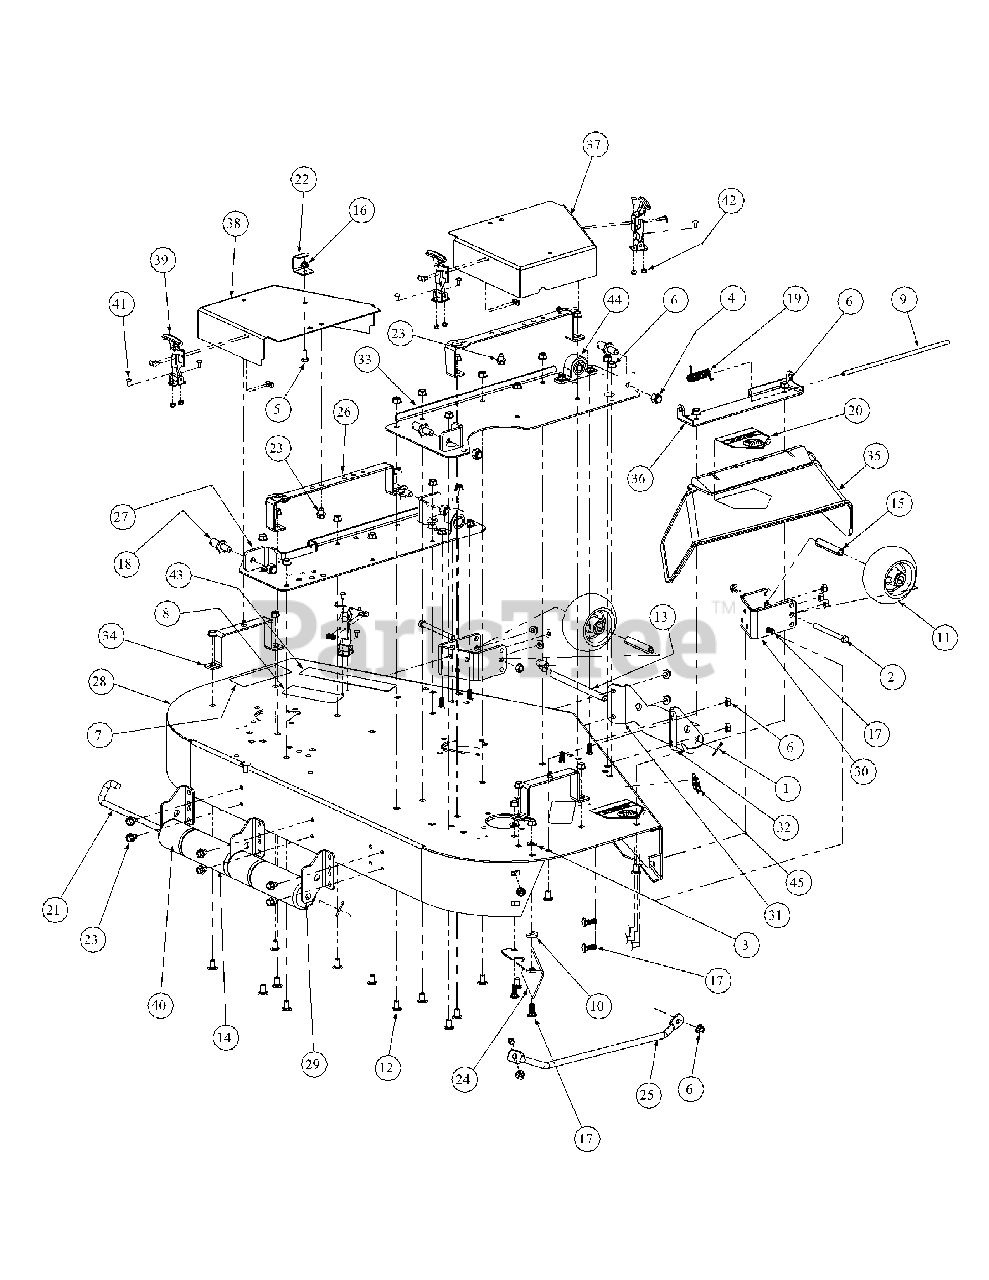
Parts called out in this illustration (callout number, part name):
1	Cotter Pin, .125 Dia. x 1.0
2	Hex Cap Screw, 3/8-16, 3.75
3	Flat Washer, 3/8
4	Lock Nut, Nylon Insert, 1/2-13
5	Hex Cap Screw, 5/16-18 x 3/4
6	Flange Lock Hex Nut, 3/8-16
7	Decal Rotating Blade
8	Decal Warning Shield Missing
9	Chute Deflector Rod
10	Idler Washer
11	Complete Wheel, 5.00 Dia
12	Carriage Bolt, 3/8-16 x .75 Lg
13	Roller Pin, 1/2 Dia x 7.31 Lg
14	Front Roller
15	Wheel Spacer
16	Hex Flange Lock Nut, 5/16-18
17	Carriage Bolt, 3/8-16 x 1
18	Pin, 5/8 Dia. x 1.2 Lg.
19	Torsion Spring, 0.4 ID x 2.16 LG
20	Decal, Danger Hands and Feet
21	Roller Rod
22	Bracket Stop Tension Rod
23	Hex Index Washer Screw, 3/8-16, .05
24	Fabricated Deck, Chute Bracket
25	Fabricated Deck Finger Guard
26	Fabricated Belt Support Cover
27	Left Hand Deck Bracket Assembly
28	48 Fabricated Deck Assembly
29	Fabricted Deck Roller Mount Bracket
30	Front Anti-Scalp Wheel Mount Bracket
33	Right Hand Deck Bracket Assembly
34	Outer Belt Cover Support Assembly
35	Deflector Chute
36	Deflector Chute Bracket
37	Right Hand Belt Cover
38	Left Hand Belt Cover
39	Latch Drawing, T-Handle
41	Phillip Head Screw, 10-32
42	Lock Nut, Nylon Insert, 10-32
44	Pillow Block
45	Decal, 48"
